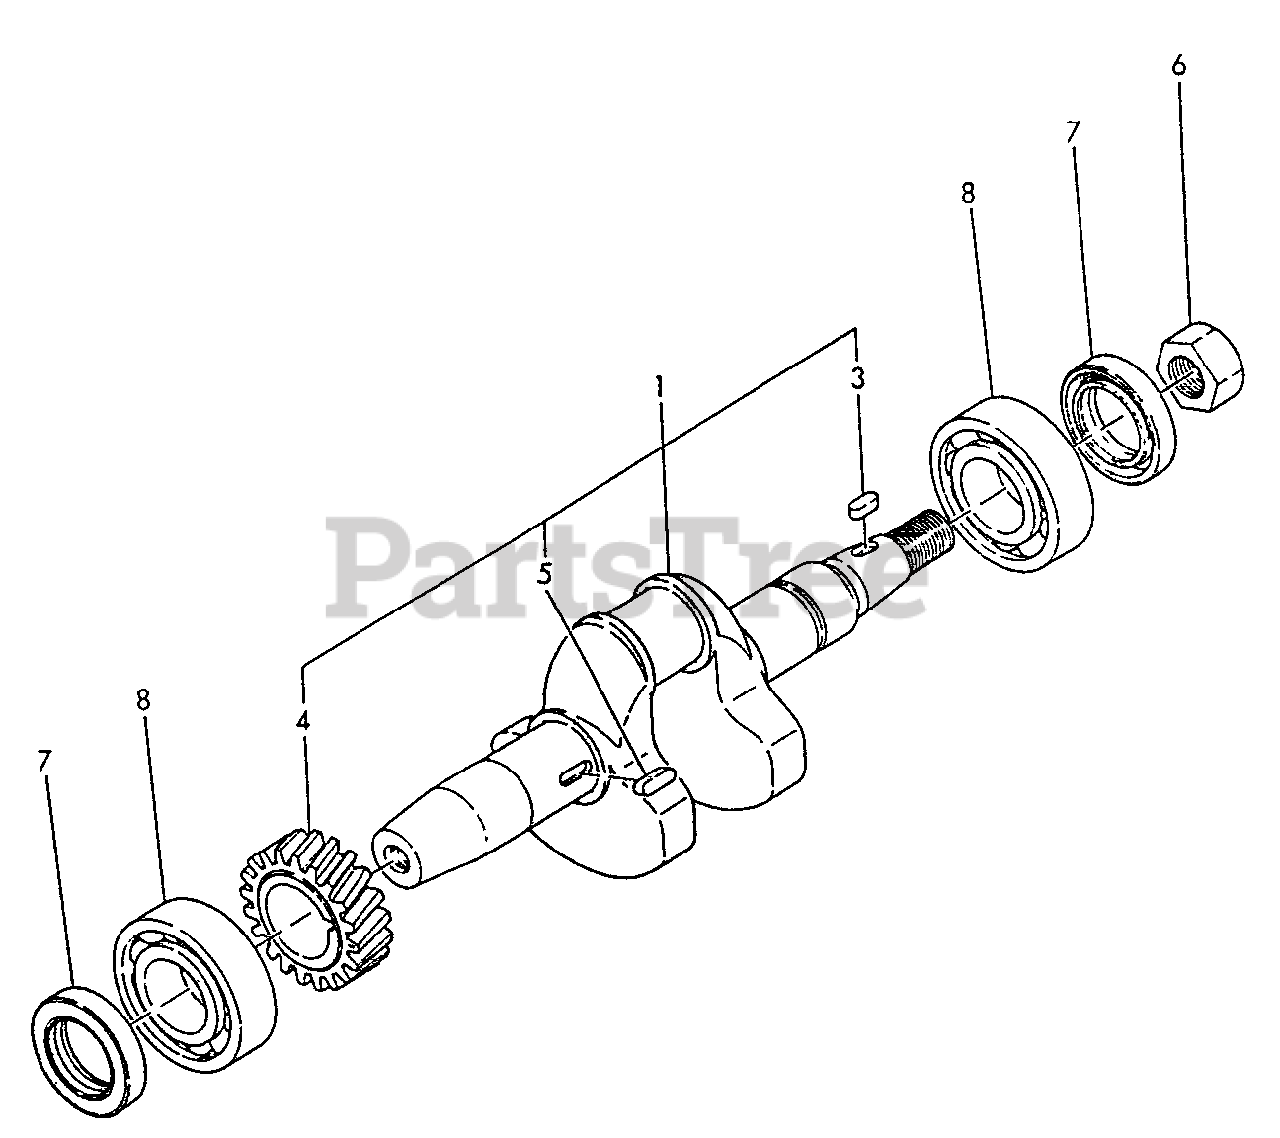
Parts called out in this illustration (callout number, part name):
1	CRANKSHAFT ASSY
3	KEY - 4X10
4	GEAR, CRANKSHAFT
5	KEY - 4X12
6	NUT - 14
7	SEAL, OIL
8	BEARING, BALL - 6205C3
